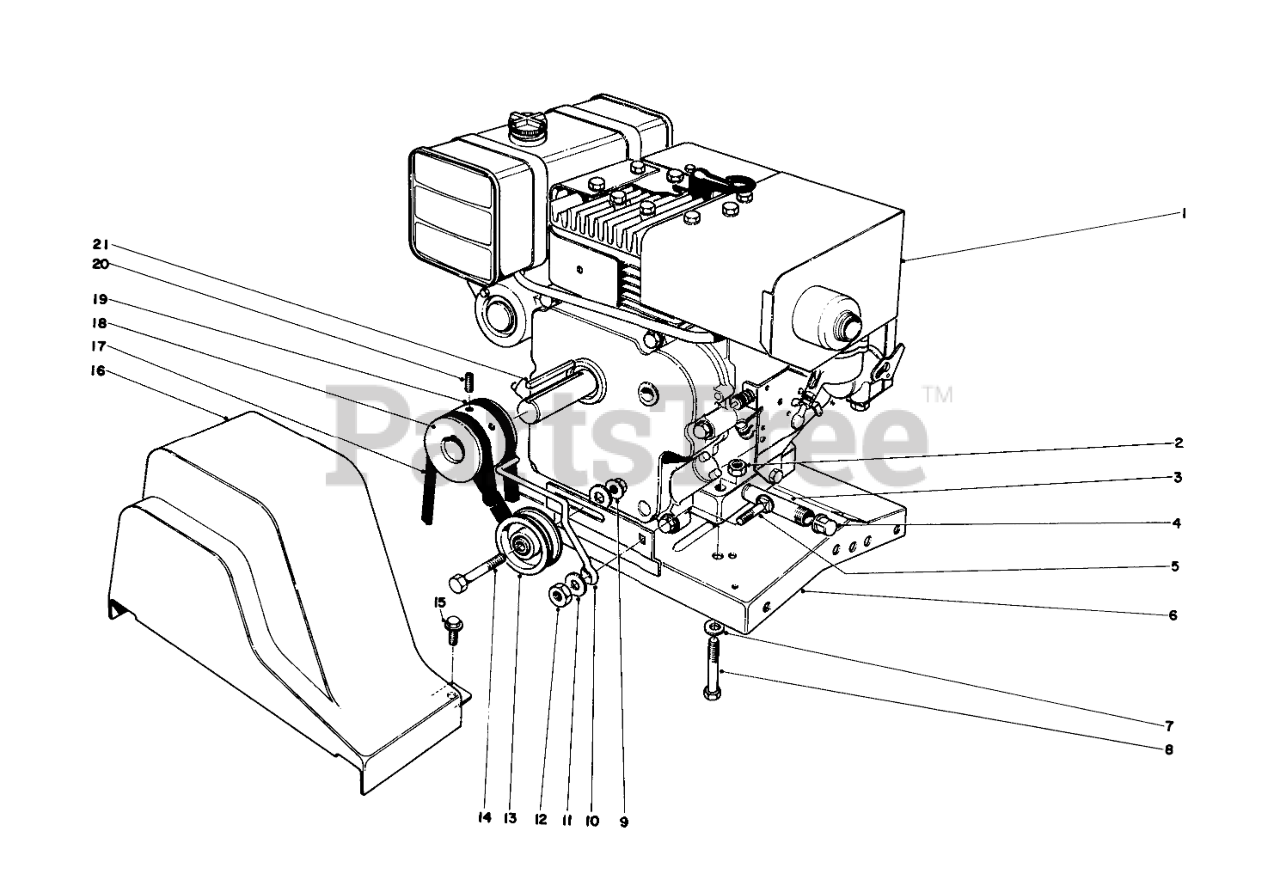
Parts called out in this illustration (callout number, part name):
1	Engine
2	NUT-LOCK, CONE
3	NIPPLE-PIPE
4	CAP-PIPE
5	SCREW-CARR
6	Engine Base
7	WASHER-PLAIN
8	SCREW-HH
9	NUT-HHF, WHIZ
10	BELT GUIDE
11	WASHER-FLAT
12	NUT-HEX
13	PULLEY-IDLER
14	SCREW-HH
15	SCREW-HWH
16	BELT GUARD
17	V-Belt
18	Pulley
19	V-BELT
20	Screw-Set
